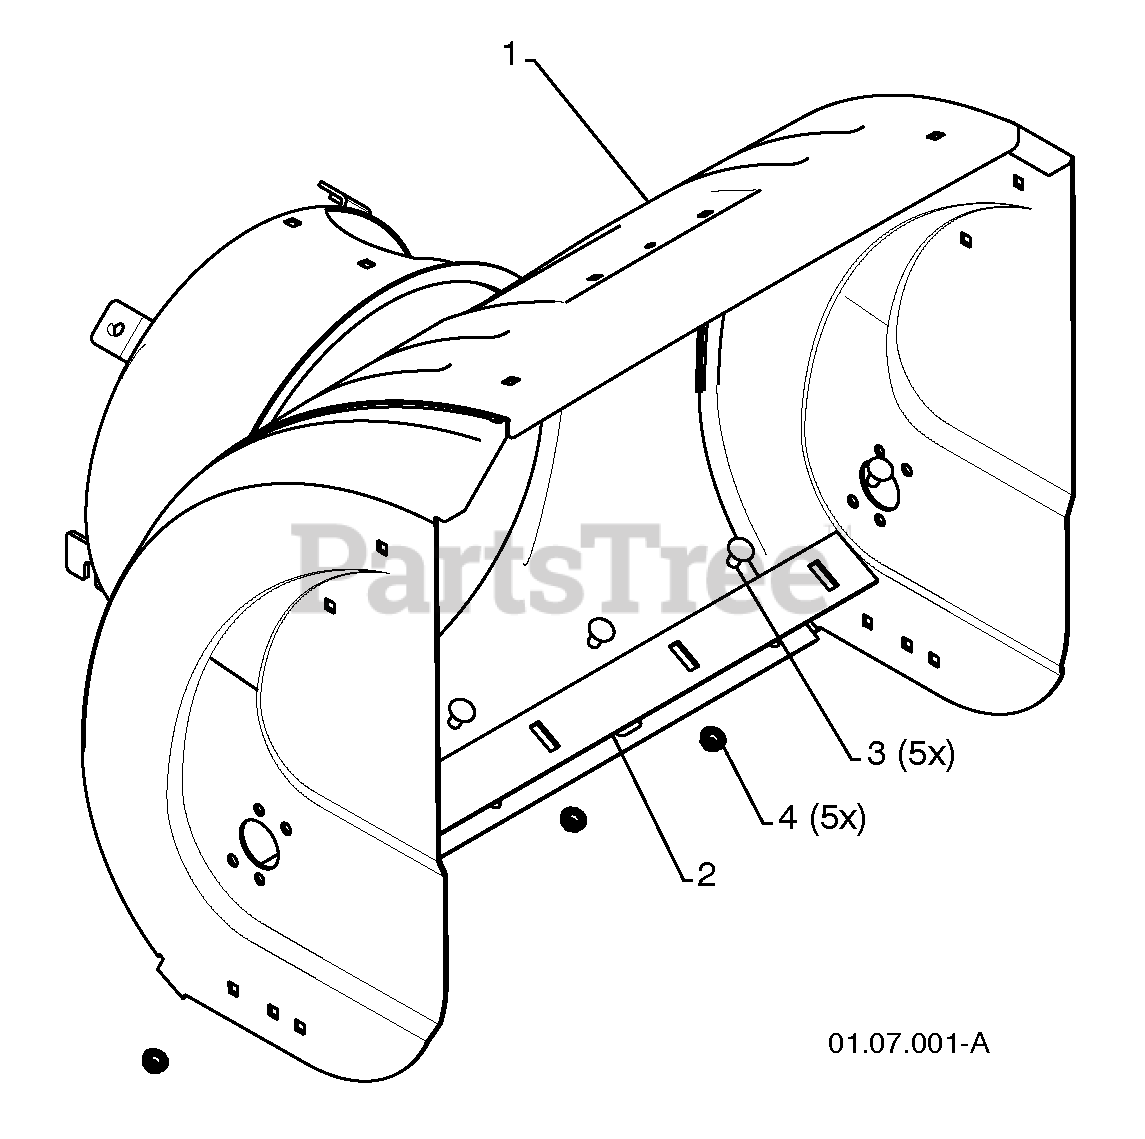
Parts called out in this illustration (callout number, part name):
1	AUGER HOUSING
2	SCRAPER BAR
3	CARRIAGE BOLT 5/16-18 X .625
4	NUT 5/16-18
